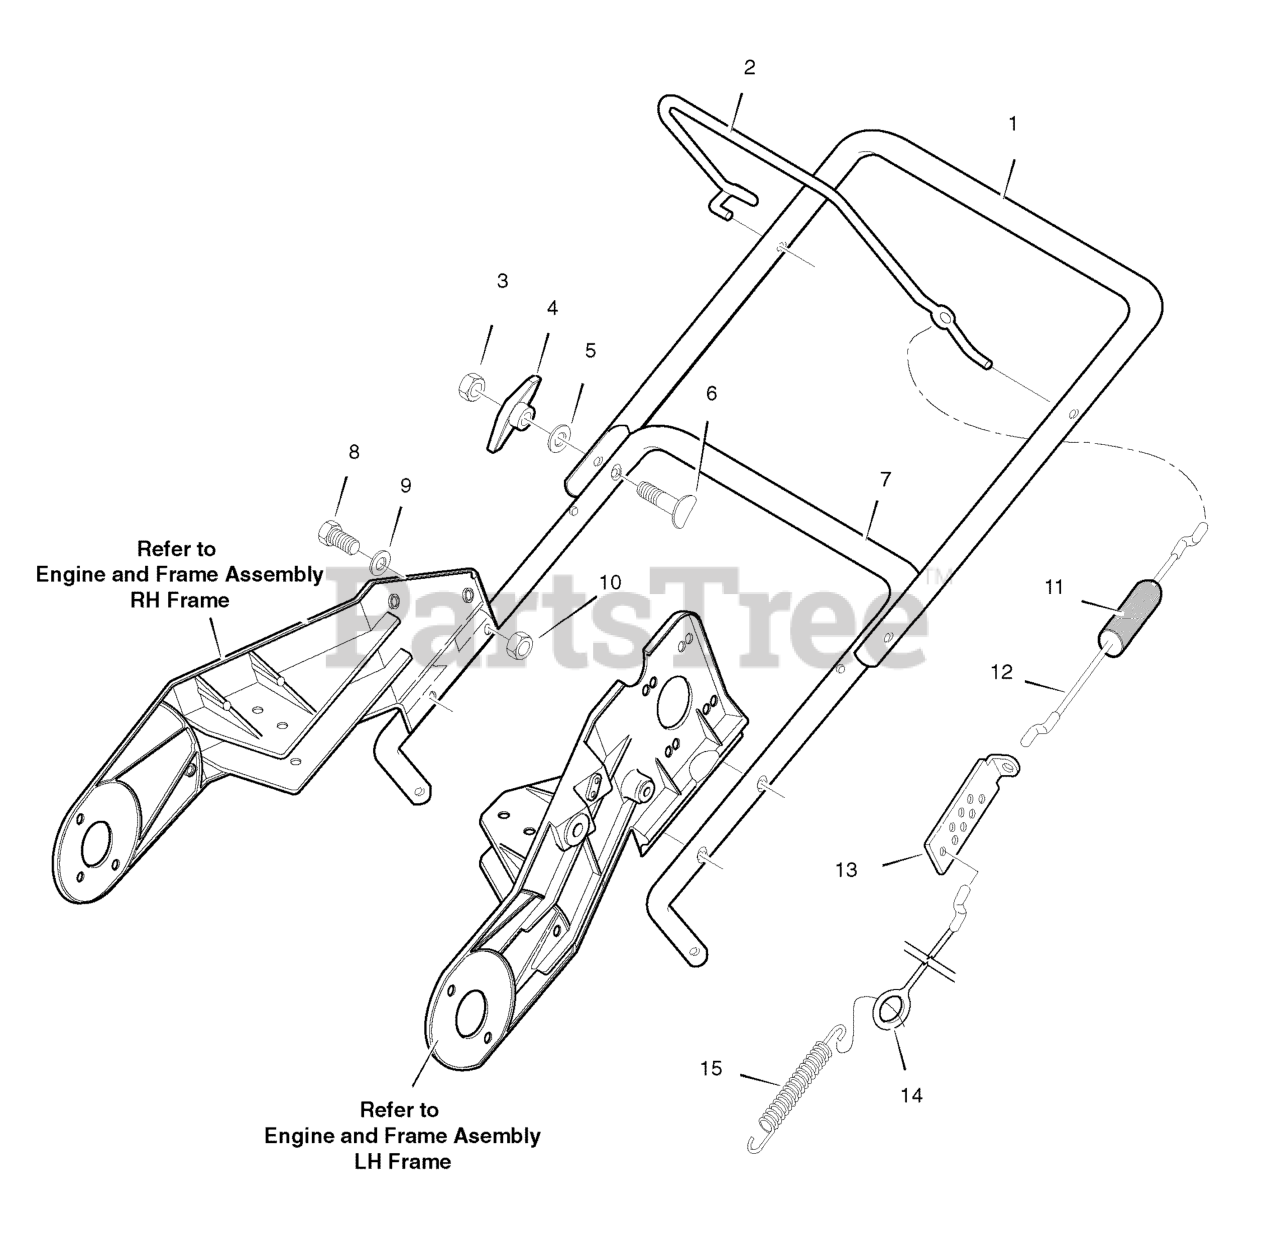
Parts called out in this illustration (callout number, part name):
1	HANDLE, UPPER
2	BAIL, CONTROL
3	NUT, 5/16-18 HEX
4	KNOB, WING
5	WASHER, FORM .344 I.D.
6	BOLT, 5/16-18 X 2.00
7	HANDLE, LOWER
8	SCREW, 1/4-20 X 1.25
9	WASHER, FLAT .281 X .63 X .065
10	NUT, .25-20 HEX CONTROL LOCK
11	BOOT, CLUTCH SPRING
12	CABLE, UPPER CONTROL
13	BRACKET, CABLE ADJUST
14	CABLE, LOWER CONTROL
15	SPRING, EXTENSION .75 O.D. X .069 X 2.00
